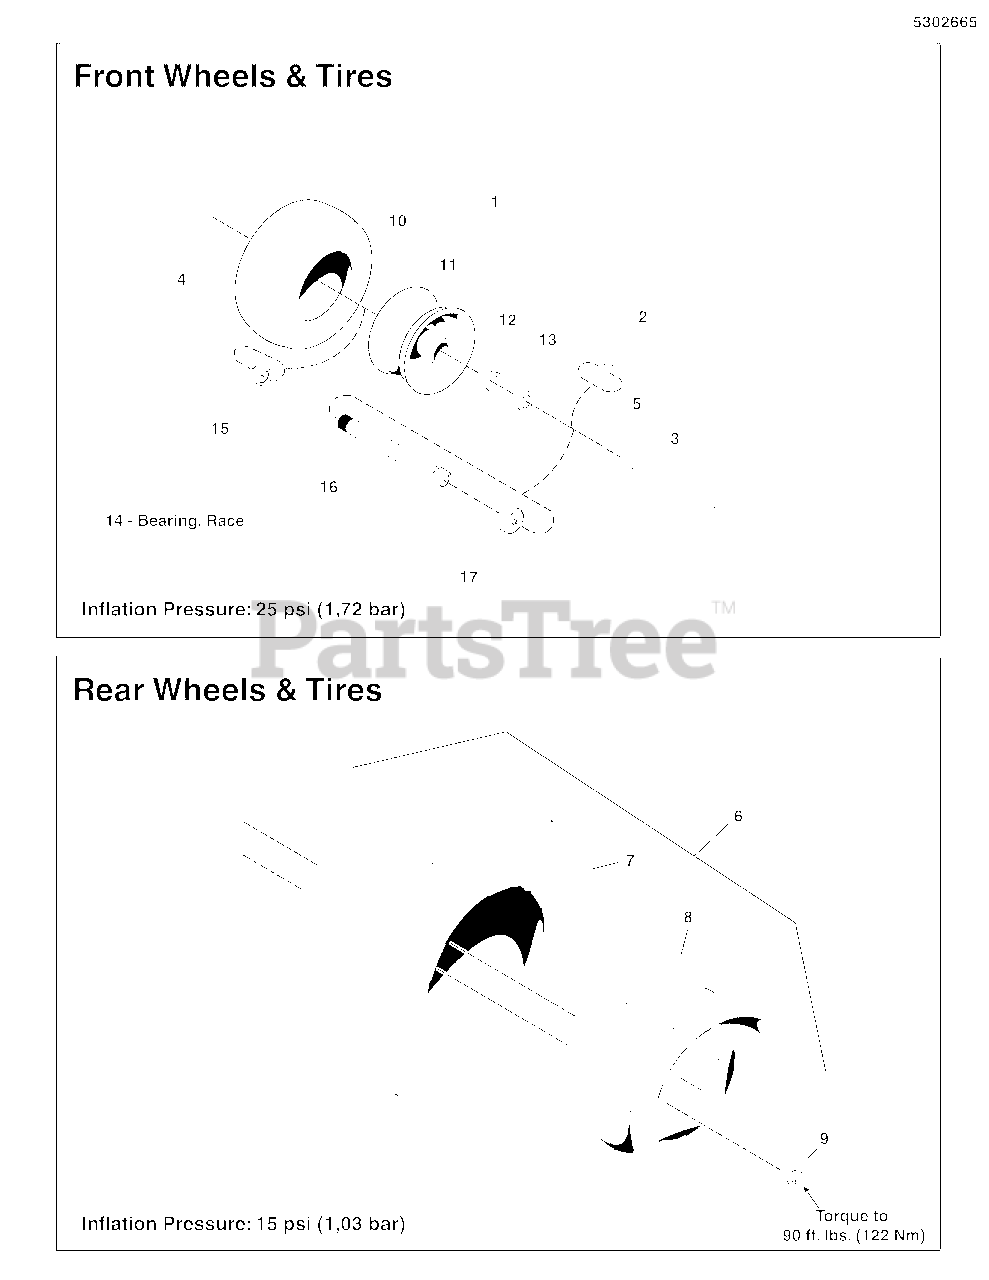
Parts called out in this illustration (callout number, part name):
1	TIRE, CASTER, 13 X 5.00-6
2	ADAPTER, CASTER AXLE, CZ
3	BOLT, 1/2-13 x 8"
4	NUT, 1/2-13 HEX NYLOCK FLANGE
5	WASHER, 1/2 SAE
6	TIRE ASSM, 22X11.00-10, .75 NEG
7	TIRE, 22 X 11.00-10, 4 PLY
8	WHEEL, 10 X 7, .75NEG OFFSET
9	NUT, 1/2-20, FOR WHEEL BOLT SILVER
10	TIRE, 13 X 5.0 - 6
11	WHEEL ASSEMBLY, 13 X 5 - 6 TIRE
12	BEARING, Tapered Roller
13	SEAL, GREASE
14	BEARING, RACE
15	NUT, BEARING ADJUSTER, AXLE
16	AXLE, BEARING ADJUSTER, 6.0"
17	DEBRIS COVER, CASTER WHEELS
